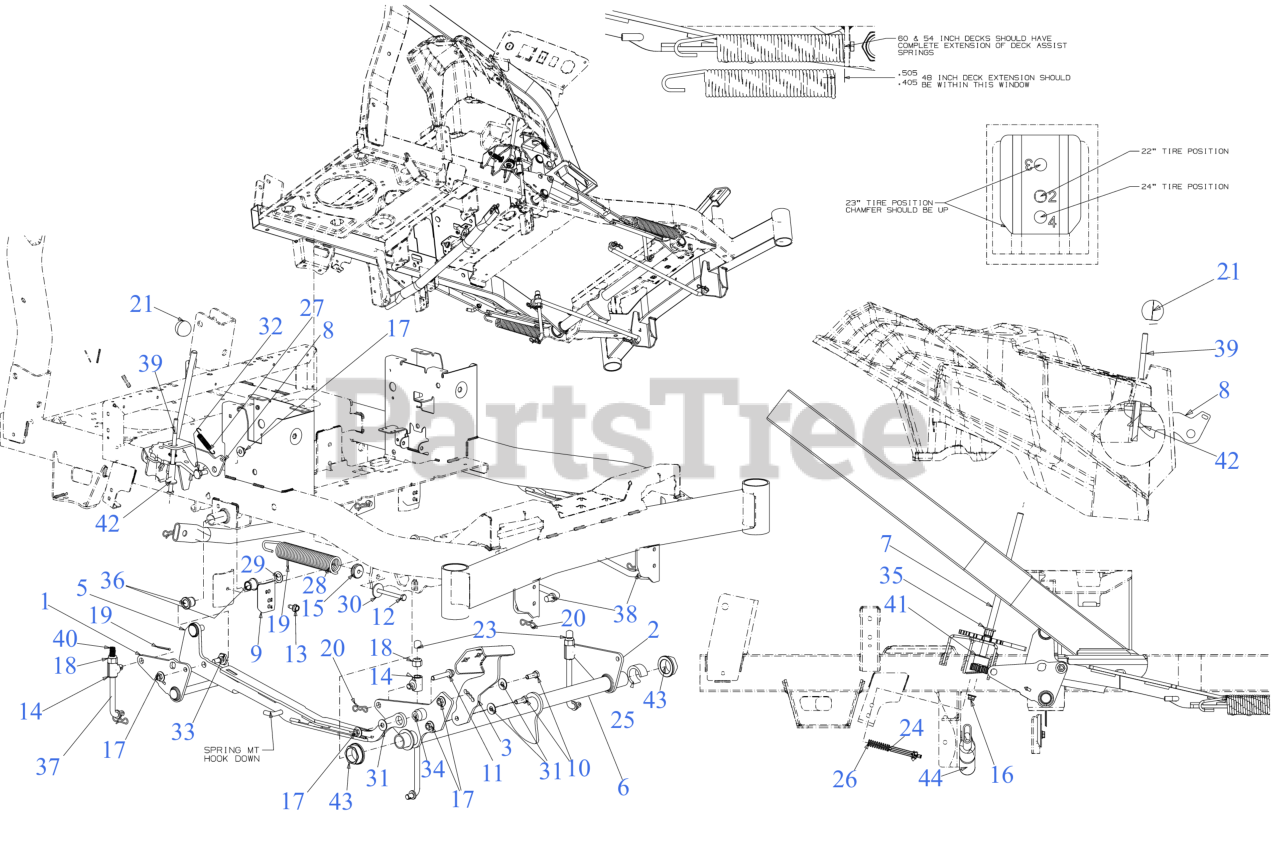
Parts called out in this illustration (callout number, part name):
1	BELLCRANK BRACKET (RH)
2	BELLCRANK BRACKET (LH)
3	DECK LIFT PEDAL
5	LIFT LINK (RH)
6	LIFT TUBE (FRONT)
7	DECK HEIGHT ADJUSTMENT ROD
8	TRAVEL LOCK PLATE
9	UPSTOP BRACKET
10	SCREW 3/8-16 x 1 GR5
11	SCREW 3/8-16 x 2.00 GR5
12	SCREW 5/16-18 x 3.50 GR5
13	SCREW 5/16-18 x .750
14	LIFT ROD FERRULE
15	LIFT SPRING INSERT
16	FLANGE LOCK NUT 5/16-18
17	FLANGE LOCK NUT
18	HEX LOCK NUT NYLON
19	COTTER PIN
20	BOW TIE COTTER PIN
23	LIFT ROD END CAP
24	DETENT PLUNGER
25	LIFT TUBE SPACER
26	COMPRESSION SPRING .531 OD 1.75 LG
27	EXTENSION SPRING 2.675"
28	EXTENSION SPRING
29	FLAT WASHER
30	WASHER-5/16 x 1.25X 1.27
31	WASHER-.395 x 1.0 x .62
32	SHOULDER SCREW
33	SHOULDER SCREW .50 x .385
34	SHOLUDER SPACER
35	HEX FLANGE BEARING .506ID x .590LG
36	FLANGE BUSHING
37	DECK LIFT ROD 6.875"
38	DECK CONTROL ROD
39	TRAVEL LOCK ROD
40	DECK LIFT ROD 6.250"
41	DECK HEIGHT DETENT HUB
42	LOCK ROD SLEEVE SPACER
43	FLANGE BEARING
44	DECK STABILIZER TUBE
